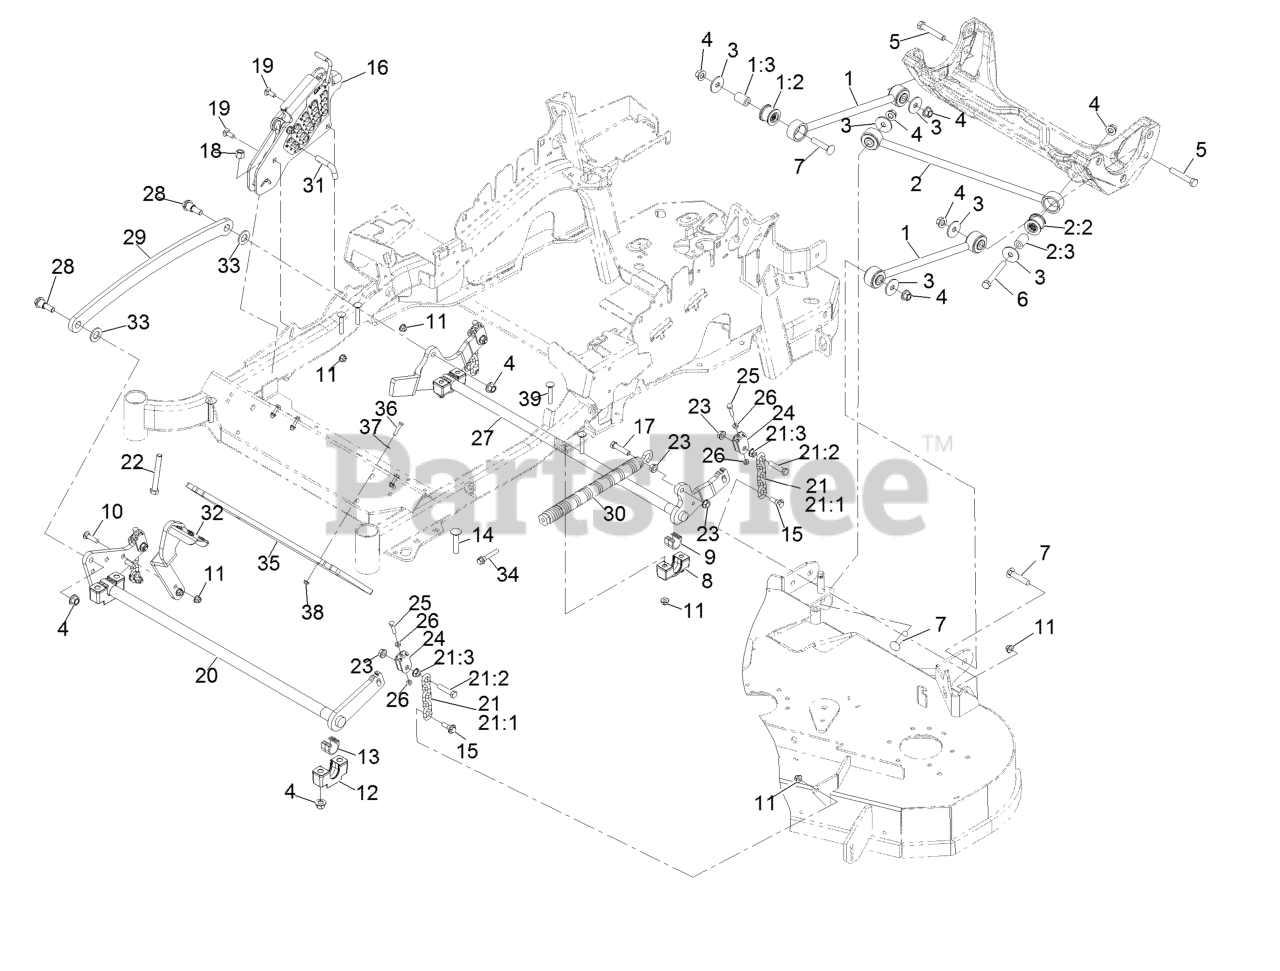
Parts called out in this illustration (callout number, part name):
1	Deck Strut ASM
1:2	Bushing-Suspension, Rubber
2	Panhard Rod ASM
2:2	Bushing-Suspension, Rubber
4	Nut-Lock 1/2-13
5	Screw-HH 1/2-13 X 3
6	Screw-HH 1/2-13 X 4
7	Bolt-Carriage 1/2-13 X 2 1/2
8	Support-Cross Shaft, Bearing Rear
9	Bearing-Cross Shaft, Rear
10	Bolt-Carriage 3/8-16 X 1 1/2
11	Nut-Nyloc 3/8-16 Flg
12	Support-Cross Shaft, Bearing
13	Bearing-Cross Shaft, Front
14	Bolt-Carriage 1/2-13 X 2 1/2 Spl Neck
15	Screw-Hex Flange 3/8-16 X .80
16	HOC ASM
17	Screw-HH 7/16-14 X 2
18	Nut-Nyloc 1/2-13
19	Bolt-Carriage 3/8-16 X 1
20	Decklift-Front
21	Deck Lift Chain ASM
21:1	Chain-Lift, Deck
21:2	Screw-HH 7/16-14 X 2
21:3	Nut-Whizlock 7/16-14
22	Bolt-HH 1/2-13 X 4 Tap
23	Nut-Whizlock 7/16-14
24	Yoke-Adjust, Deck
25	Screw-HH 5/16-18 X 1 1/4
26	Nut-Jam 5/16-18
27	Lift-Deck, Rear
28	Screw-Shoulder HHF 1/2-13 X 1.12
29	Link-Lift, Deck
30	Spring-Extension
31	Pin-HOC
32	Lever-Foot
33	Washer-3/4 SAE
34	Screw-Shcs 3/8-16 X 2.212
35	Weight-Toe Board
36	Screw-HH 1/4-20 X 1 1/4
37	Washer-1/4 SAE
38	Nut-Nyloc 1/4-20 Flg
39	Bolt-Carriage 3/8-16 X 2 1/4
